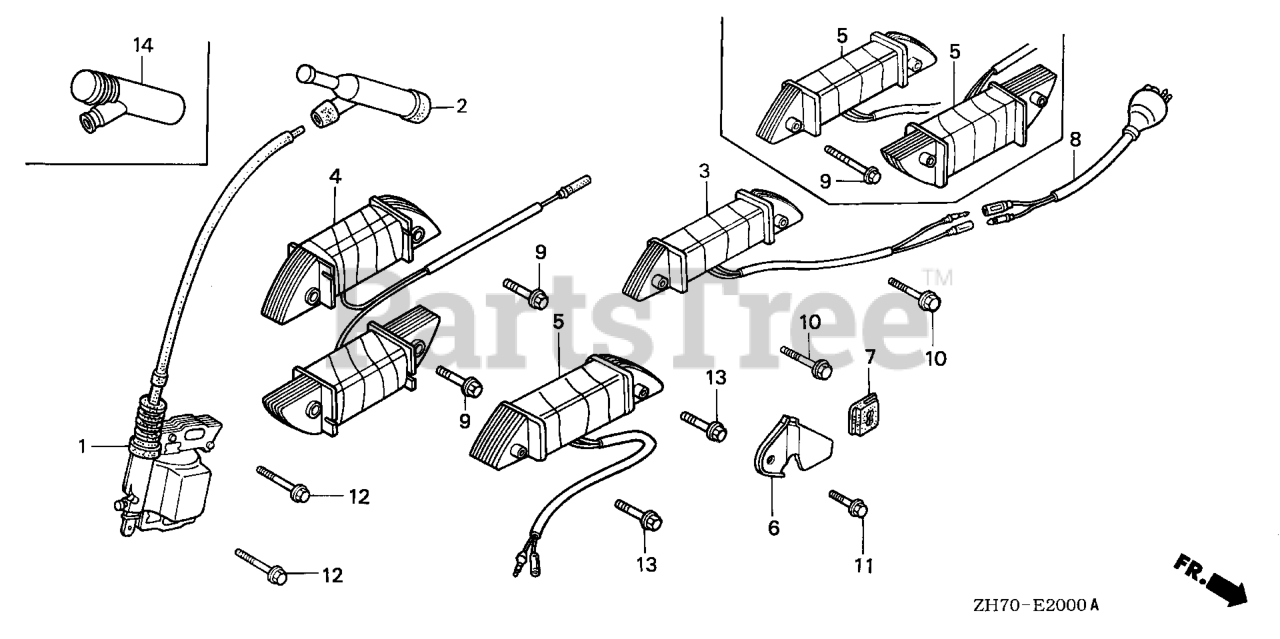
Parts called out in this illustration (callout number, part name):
1	COIL ASSY., IGNITION Use up to Engine SN 1530314.
2	CAP ASSY., NOISE SUPPRESSOR (Honda Code 3526837). (NICHIWA Y-EZ RTFM256)
12	BOLT, FLANGE (6X25) Use up to Engine SN 2056819.
